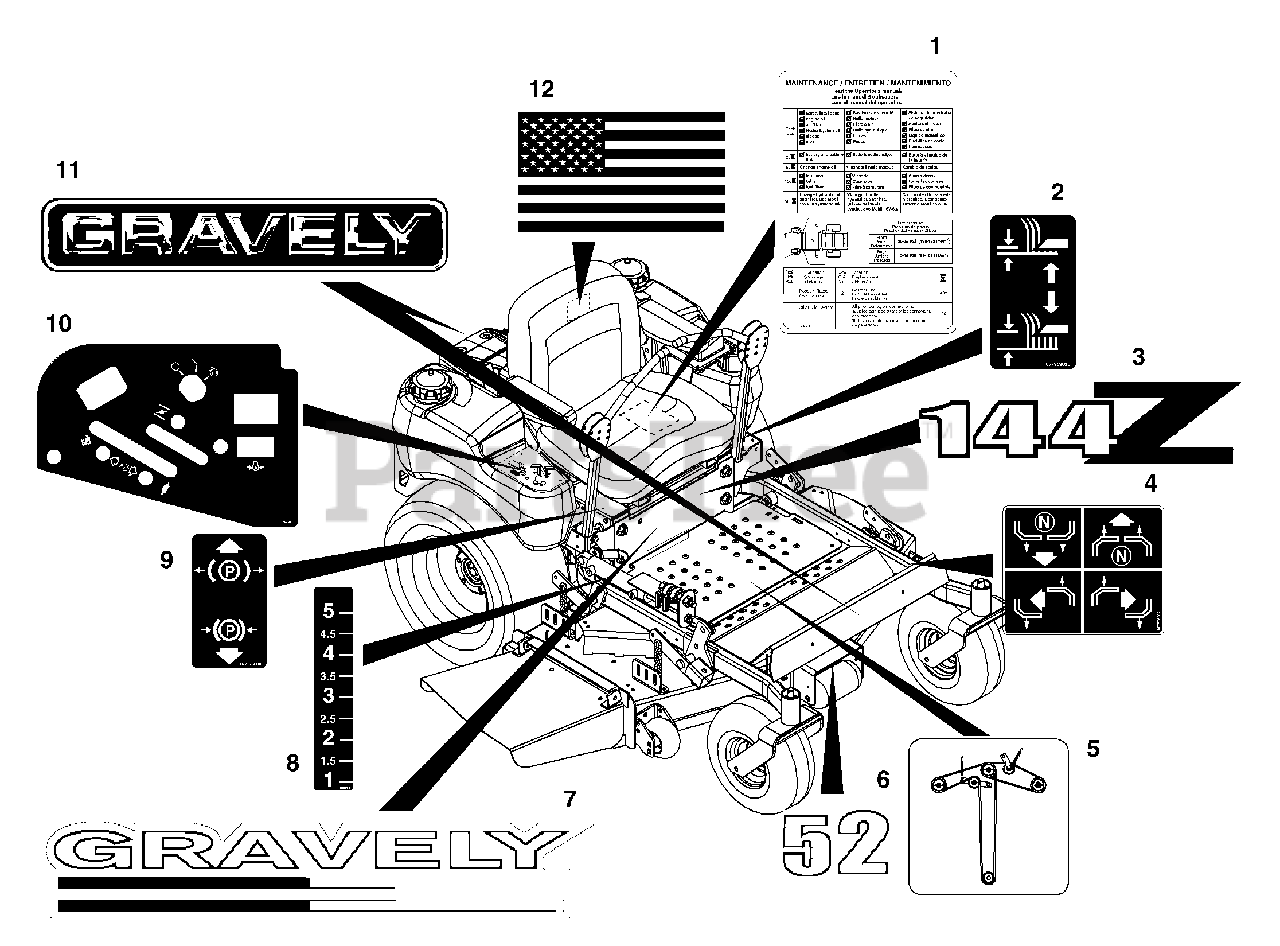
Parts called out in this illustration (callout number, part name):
1	Decal, Service Instructions
2	Decal, Lift Lever
3	Decal, PM 152Z (079, 081)
3	Decal, PM 144Z (077)
3	Decal, PM 148Z (078)
3	Decal, PM 160Z (080, 082)
4	Decal, Instructional Steering
5	Decal, Belt Diagram
6	Decal, 52 (079, 081)
6	Decal, 44 (077)
6	Decal, 48 (078)
6	Decal, 60 (080, 082)
7	Decal, ZT Hood
8	Decal, Height of Cut
9	Decal, Parking Brake Lever
10	Decal, Control Panel
11	Decal, 15" Gravely Logo
12	Decal, American Flag
